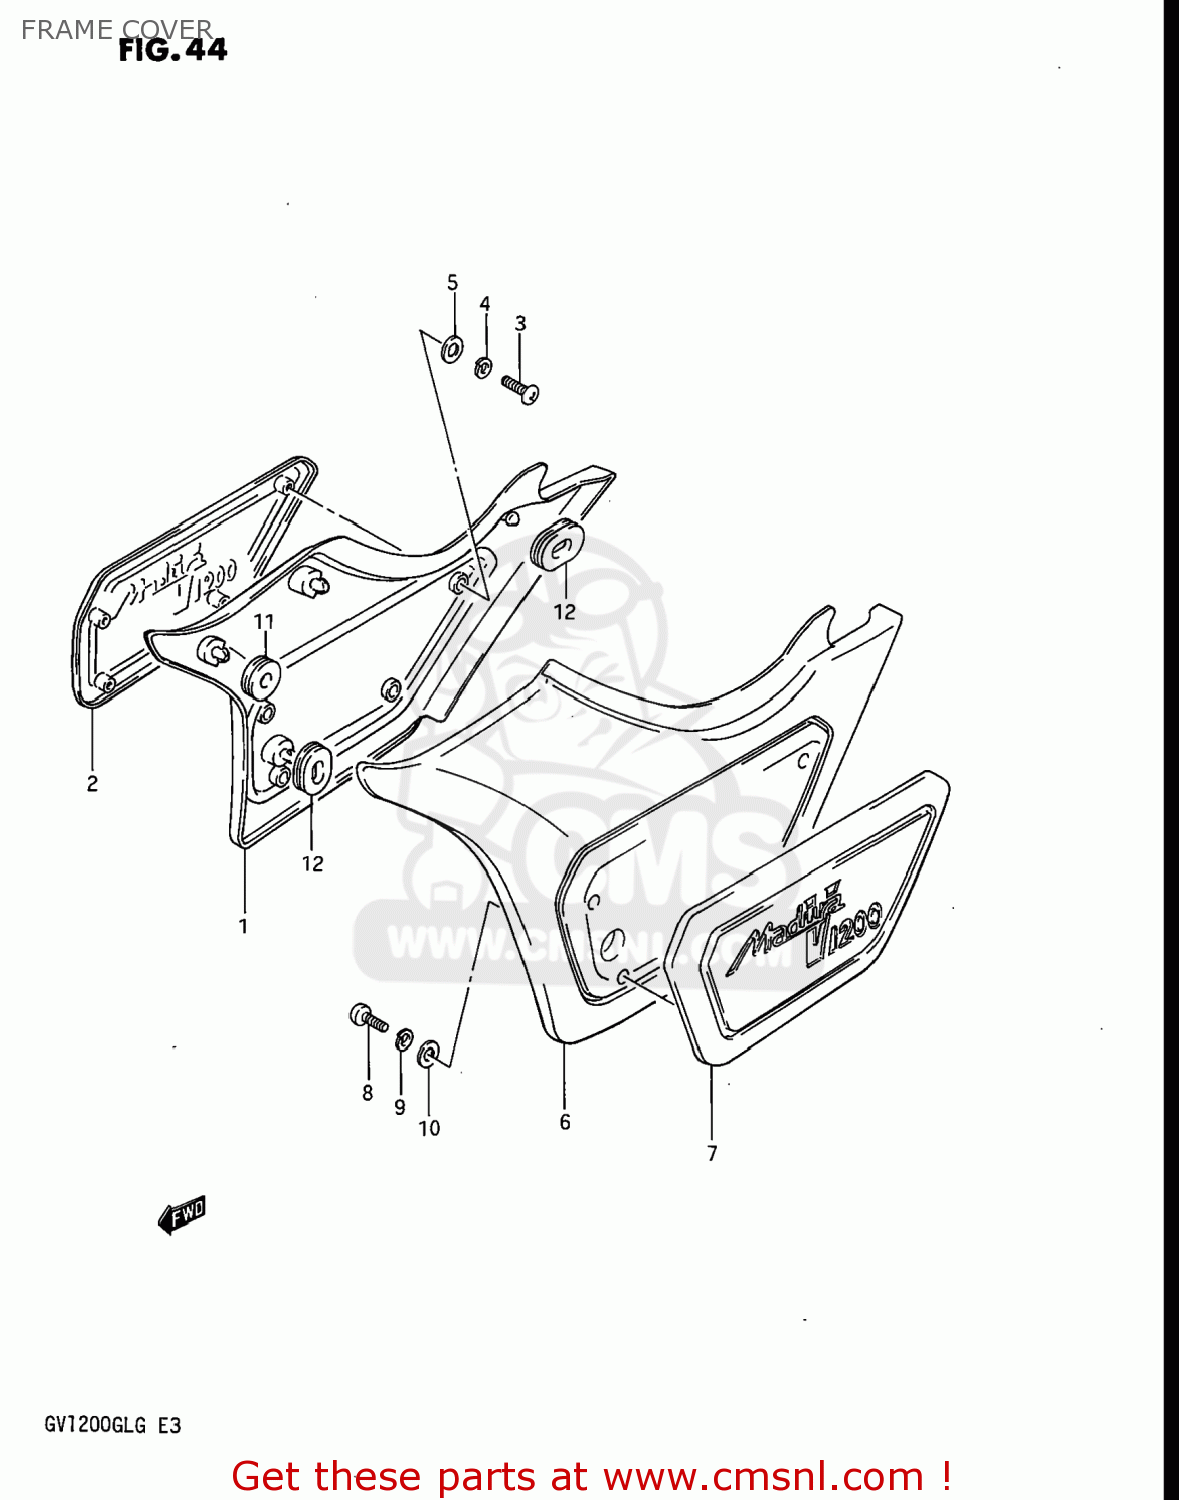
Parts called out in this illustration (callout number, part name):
1	COVER,FRAME,RIGHT
2	COVER,FRAME
3	SCREW
4	LOCK WASHER
5	WASHER (4X14X1.2)
6	COVER,FRAME,LEFT
7	COVER.FRM..NO.2
8	SCREW
9	LOCK WASHER
10	WASHER (4X14X1.2)
11	CUSHION
12	CUSHION
